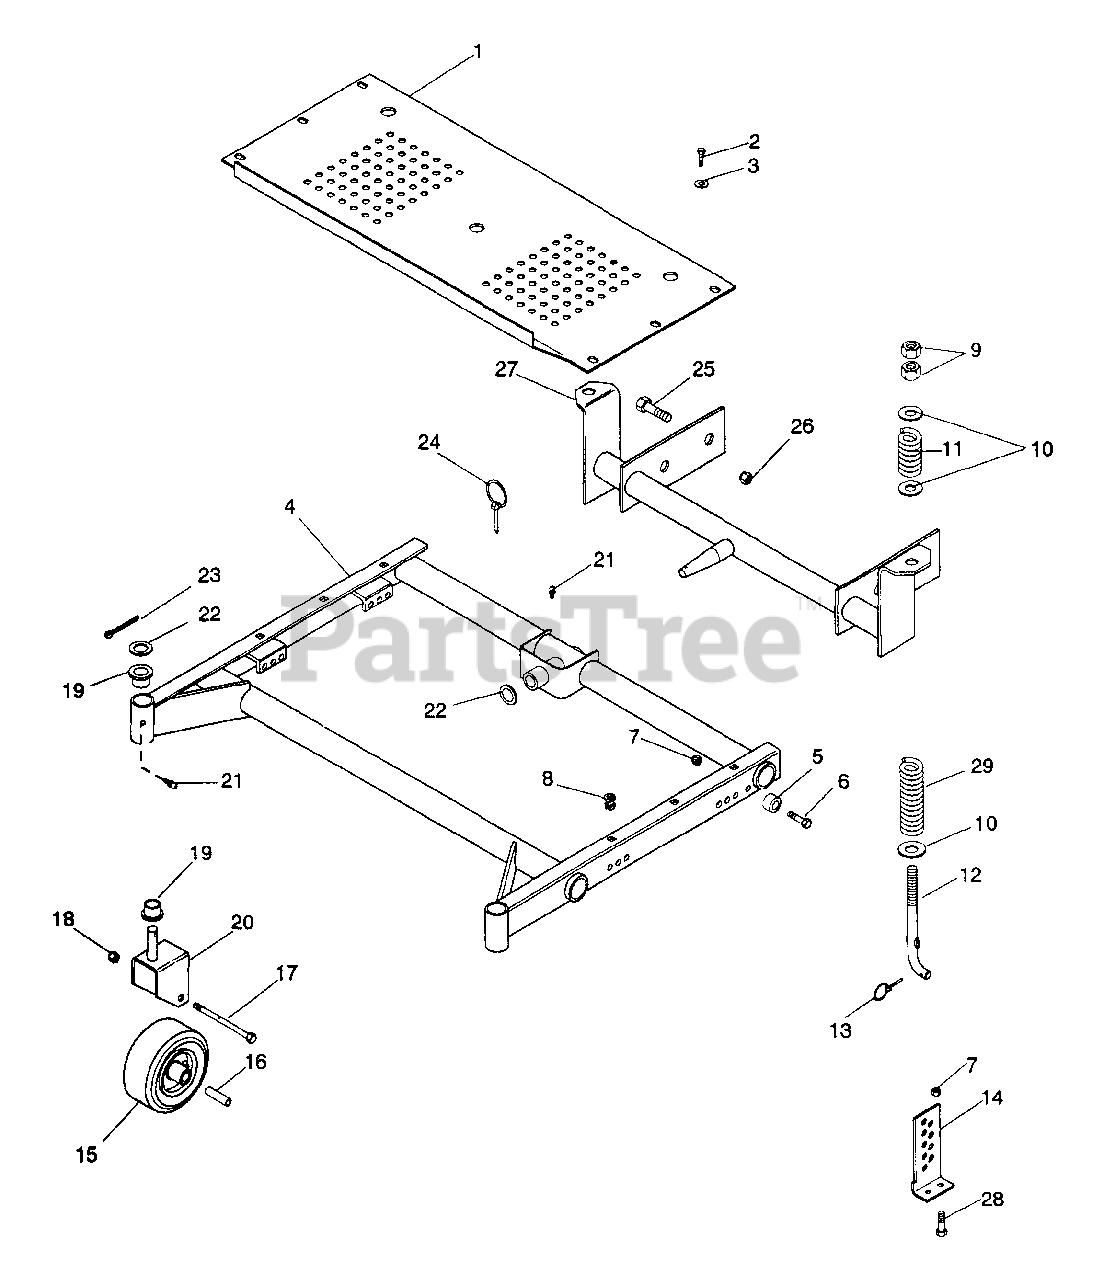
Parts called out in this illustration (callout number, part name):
1	Footboard
2	Screw-Machine .25-20 Pan Head
3	Washer-Flat-Steel .281 x .625 x .065
4	Weldment, Mower Frame
5	Bushing, 021076 W/E-Coat Finish
6	Bolt-Hex .38-16 x 1.50 Pl Gr. 5
7	Nut-Lock-Nylon .375 - 16 Pl
8	Clip, U-Type Easton #C17453-1420
9	Nut, 50-13 Pl
10	Washer-Flat-Steel .531 x 1.062 x .095
11	Spring-Compression .188 x 1.66 x 2.0
12	Rod, Height Adjustment
13	Pin-Kilk 1.00 x .188 x 1.25
14	Bracket, Rear Adjustment R.H.
14	Bracket, Rear Adjustment L.H.
15	Wheel, Gage 11 x 4 - 4
16	Bushing, Caster Fork
17	Bolt-Hex .50-13 x 6.50
18	Nut-Lock-Nylon .50-13 Pl
19	Bushing-Flange 1.020 x 1.75 x .75 Nylon
20	Weldment, Caster Fork
21	Fitting, Lube .25-28 Self-thread
22	Bearing-R-Thrust 1.002 x 1.552 x .030
23	Pin-Cotter .188 x 1.50
24	Pin-Klik .25 x 1.75
25	Bolt-Hex .625 - 11 x 1.50
26	Nut, Lock 5/8 - 11 Hex W/Insr
27	Weldment, Mower Frame Mounting
28	Bolt-Carriage .38 - 16 x .75
29	Spring-Compression .095 x .75 x 6.25 Wld 35
